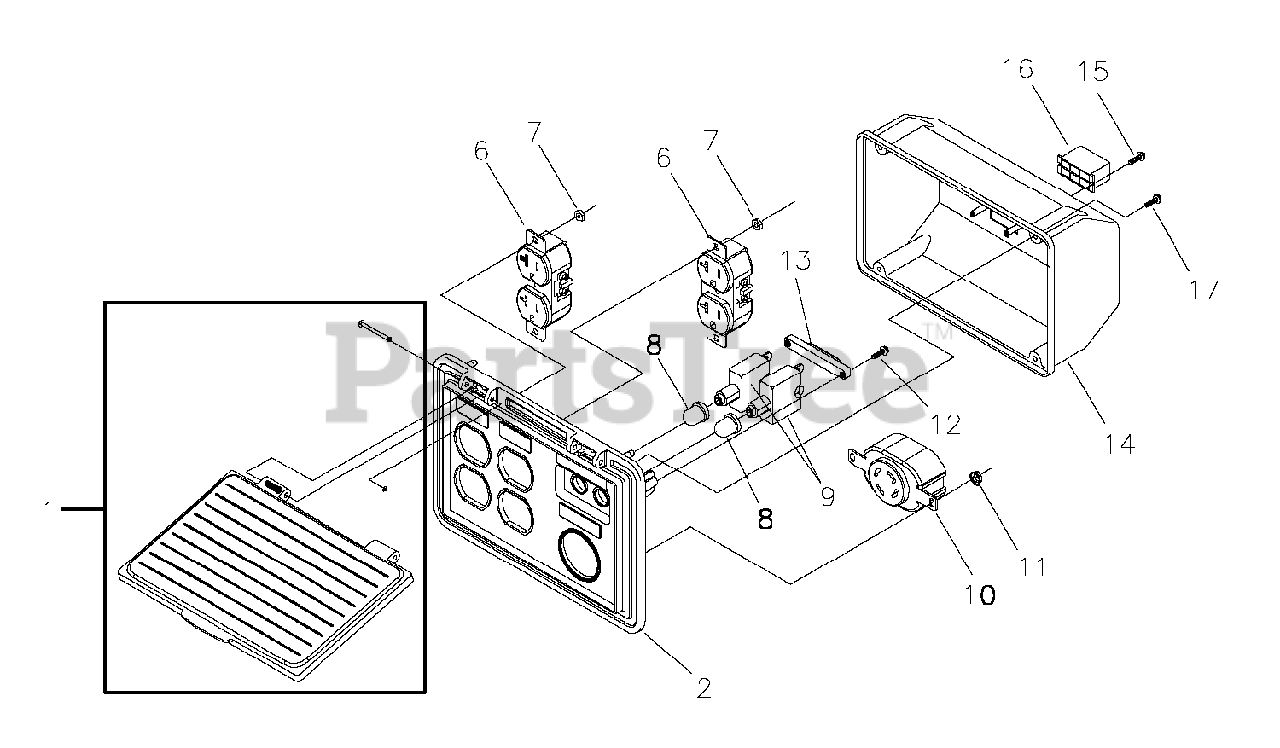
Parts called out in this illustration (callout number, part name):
1	KIT,Control Panel Lid
2	CONTROL PANEL,Compact
6	OUTLET,120V,20A,Duplex
8	CAP,Breaker,Circuit
9	BREAKER,Circuit
10	OUTLET,120/240V Locking,30A
13	BAR,Retaining
14	COVER,Back,Control Panel
16	HOUSING,Receptacle
